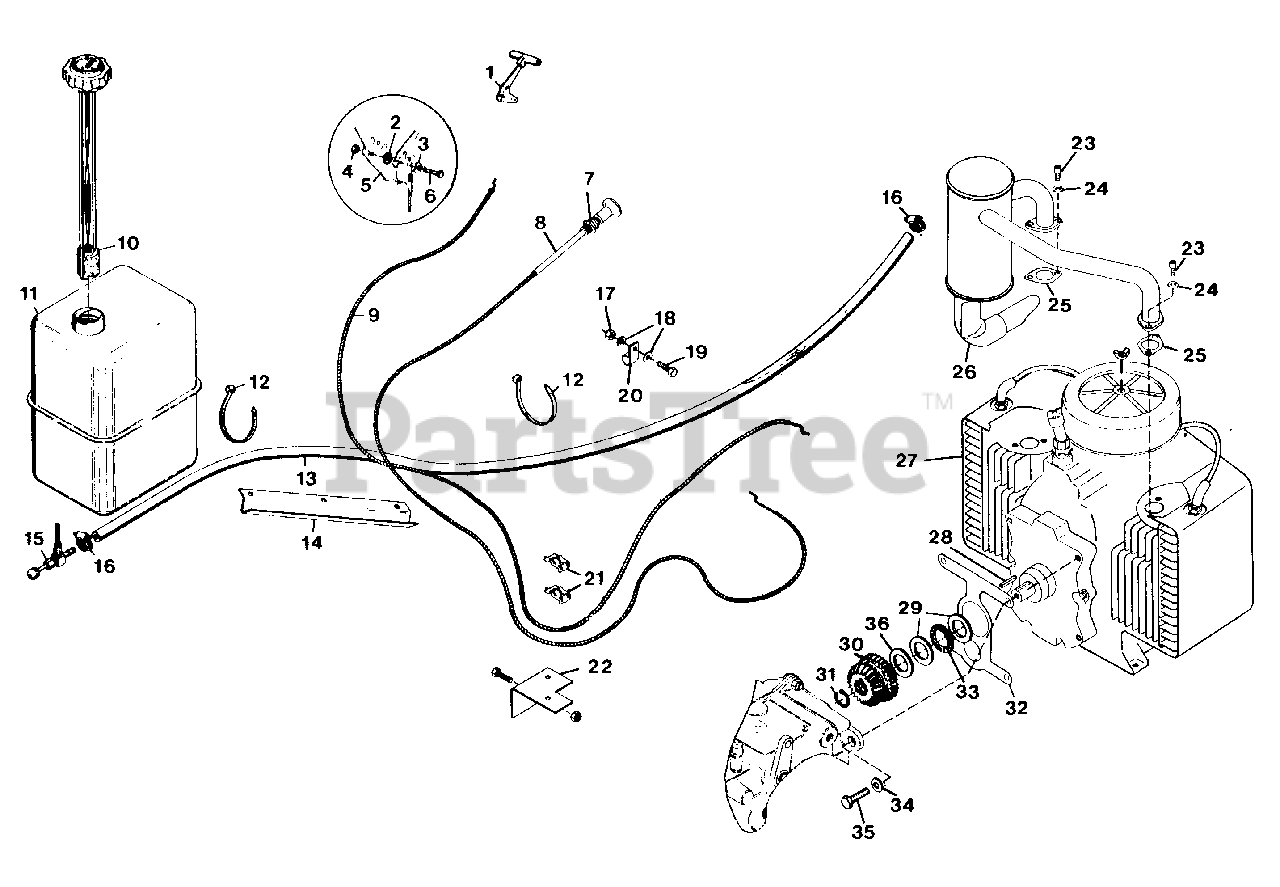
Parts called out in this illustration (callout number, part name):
1	ASSEMBLY, KNOB AND LEVER
2	WASHER, FRICTION
3	WASHER, SPRING
4	NUT, LOCK 1/4-28
5	BRACKET, MOUNTING
6	BOLT, HEX 1/4-28X.75
7	NUT, JAM 3/8-24 HEX
8	CONTROL, CHOKE
9	ASSEMBLY, CHOKE CONDUIT
10	GAUGE, GAS
11	TANK, FUEL
12	TIE, CABLE
13	LINE, FUEL
14	SHIELD, HEAT
15	VALVE, FUEL 90 DEG. REVERSE FLOW
16	CLAMP, HOSE
17	NUT, LOCK 5/16-18
18	WASHER, FLAT .343X.688X.065
19	BOLT, HEX 5/16-18X1.00
20	CLAMP, NYLON
21	CLIP, SPEED
22	BRACKET, THROTTLE AND CHOKE
23	SCREW, CAP 5/16-18X.75 SHD
24	WASHER, LOCK 5/16 REG.
25	GASKET, EXHAUST
26	MUFFLER, EXHAUST
27	ENGINE, 18 H.P.
27	ENGINE, 20 H.P.
28	KEY, SQUARE .250X1.250
29	RACE, BRG 1.125X1.750X.123/.126
30	GEAR, SPUR AND BEVEL, INPUT
31	RING, RETAINING 1.125 SHAFT
32	GASKET, ENGINE TO TRANSMISSION
33	BEARING, THRUST 1.127X1.740X.078
34	WASHER, LOCK 1/2 REG.
35	BOLT, HEX 1/2-13X1.75
36	SHIM, 1.125X1.750X.030
NS	NUT, LOCK 10-32
NS	SCREW, MACHINE 10-32X.50 PHD
